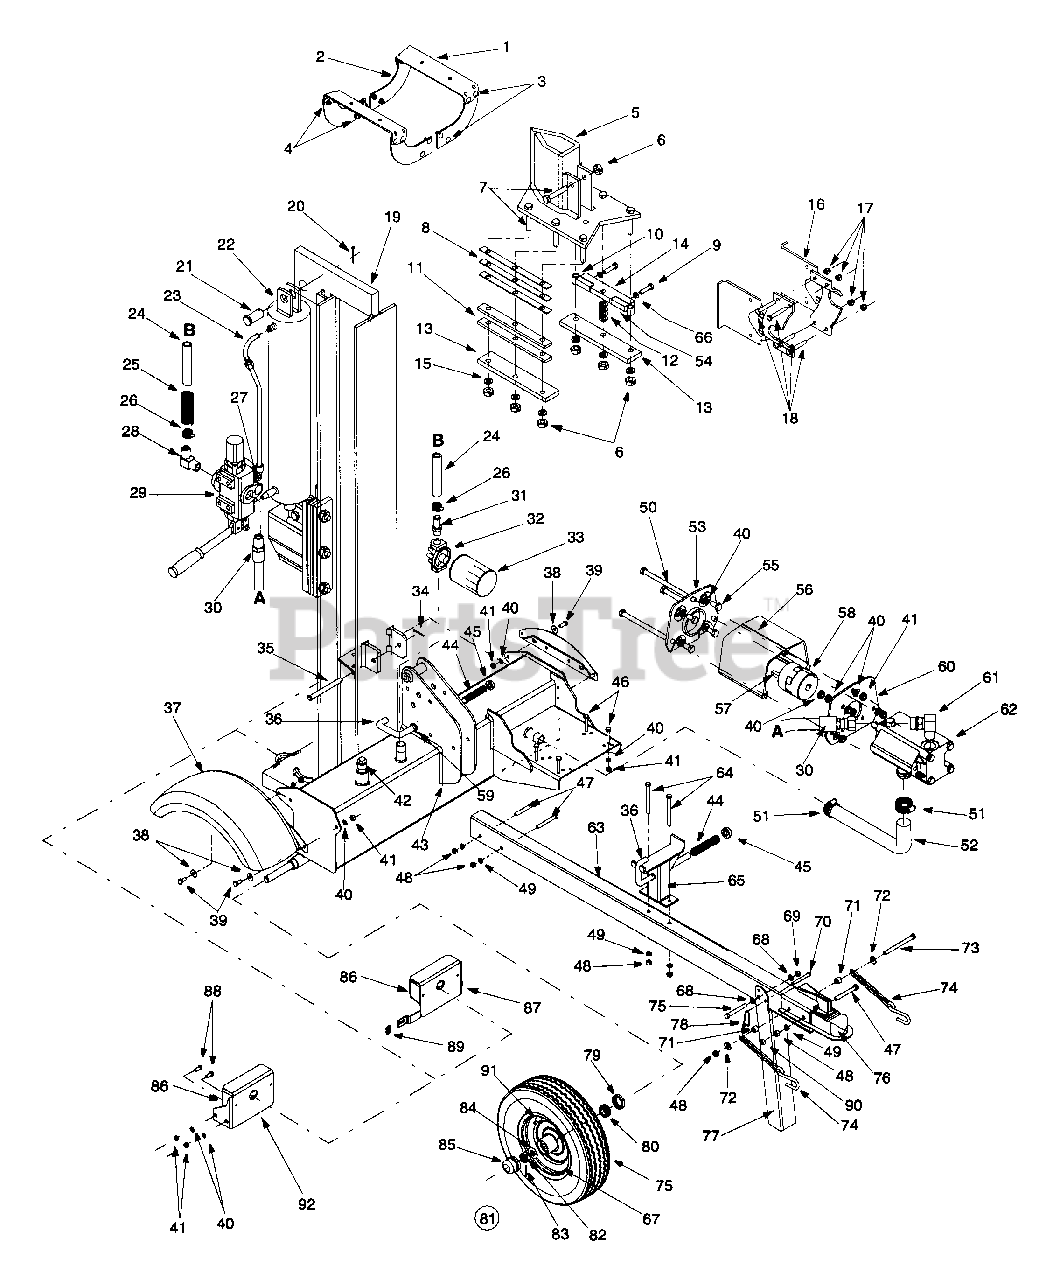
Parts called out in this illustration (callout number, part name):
1	Log Cradle
2	Log Cradle Bracket
3	Carriage Bolt, 3/8-16 x 1
4	Flanged Lock Nut, 3/8-16
5	Wedge Assembly
6	Lock Nut, 1/2-20
7	Hex Head Screw, 1/2-20 x 2.75
8	Adjustable Gib Shim
9	Hex Cap Screw, 3/8-24 x 1.5
10	Spacer
12	Flat Washer, .531 ID x .94 OD
15	Lock Washer, 1/2
18	Hex Cap Screw, 3/8-16 2.5
21	Clevis Pin
22	Hydraulic Cylinder (4.5" diameter)
23	Hydraulic Tube
24	Return Hose, 3/4 x 44 Lg
25	Hose Guard
26	Hose Clamp
27	Tube Adapter
28	Return Elbow
29	Control Valve
30	High Pressure Hydraulic Hose
31	Adapter
32	Filter Head
33	Oil Filter
34	Cotter Pin
35	Hinge Pin
36	Locking Rod
39	Hex Cap Screw, 5/16-24 x .75
40	Lock Washer, 5/16
41	Hex Nut, 5/16-24
42	Pipe Plug
45	Push Cap
46	Hex Cap Screw, 5/16-24 x 1.75
47	Hex Screw, 3/8-16 x 3
48	Hex Nut, 3/8-16
49	Lock Washer, 3/8
50	Hex Screw, 5/16-24 x 4
51	Hose Clamp
52	Suction Hose
53	Front Coupling Support Bracket
55	Hex Cap Screw, 5/16-24
56	Coupling Shield
57	Key
58	Flex Coupling
59	Flat Washer, .63 x .93 x .060
60	Rear Coupling Support Bracket
61	Adapter
62	Gear Pump (11 GPM)
64	Hex Screw, 3/8-16 x 4.0
65	Support Assembly
66	Hex Jam Nut, 3/8-24
67	Rim Assembly (Oyster Gray)
68	Flat Washer, .406" ID x .75" OD
69	Hex Lock Nut, 3/8-16
70	Clevis Pin
71	Spacer
72	Flat Washer, 3/8" ID x .87" OD
73	Hex Bolt, 3/8-16 x 4.25"
75	Tire, 16 x 4.8
76	Hitch Coupler
79	Bearing Seal
80	Tapered Bearing
81	Wheel Assembly (w/ Oyster Gray Rim)
82	Slotted Nut, 3/4-16
83	Cotter Pin
84	Flat Washer, .760 ID x .500 OD
85	Hub Cap
86	Tail Light Assembly
87	Light Bracket Assembly - LN
88	Hex Cap Screw, 5/16-24 x .75
89	Speed Clip
90	Hex Jam Nut, 3/8-16
91	Valve
92	Light Bracket - RH
